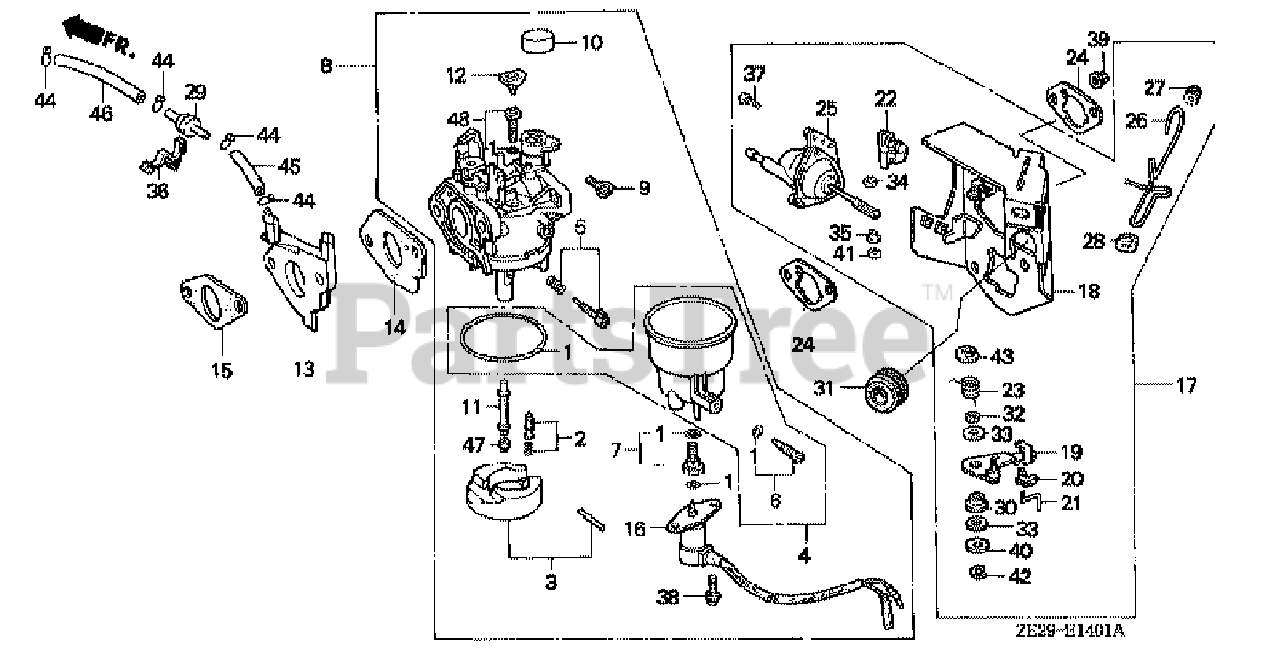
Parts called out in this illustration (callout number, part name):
1	GASKET SET
2	VALVE SET, FLOAT
3	FLOAT SET
4	CHAMBER SET, FLOAT
5	SCREW SET
6	SCREW SET, DRAIN
7	SCREW SET B
8	CARBURETOR ASSY. (BE72C)
9	SCREW, THROTTLE STOP
10	CAP, CHOKE LEVER DUST
11	NOZZLE, MAIN
12	COLLAR, SET
13	INSULATOR, CARBURETOR
14	GASKET, CARBURETOR
15	GASKET, INSULATOR
16	VALVE ASSY., SOLENOID
17	STAY ASSY., MANUAL CHOKE
18	STAY, SOLENOID
19	LEVER, CHOKE
20	JOINT, ROD
21	ROD, CHOKE
22	STOPPER, CHOKE ROD
23	SPRING, MANUAL CHOKE
24	GASKET, AIR CLEANER
25	DIAPHRAGM ASSY.
26	ROD, CHOKE CONTROL
27	GROMMET, CHOKE ROD
28	GUIDE, CHOKE ROD
29	VALVE, DASHPOT CHECK
30	BUSH, ARM PIVOT
31	GROMMET, FENDER
32	WASHER, CHOKE LEVER
33	SEAL, CHOKE LEVER
34	WASHER, THRUST (2.7X8)
35	COLLAR, LEVER
36	CLIP, WIRE HARNESS
37	SCREW, PAN (5X12)
38	SCREW-WASHER (5X12)
39	NUT, FLANGE (6MM)
40	WASHER, PLAIN (5MM)
41	E-RING (2MM)
42	E-RING (4MM)
43	E-RING (7MM)
44	CLIP, TUBE (B7)
45	BULK HOSE, VACUUM (3.5X8000) (3.5X65)
46	BULK HOSE, VACUUM (3.5X8000) (3.5X130)
47	JET, MAIN (#75)
47	JET, MAIN (#78)
47	JET, MAIN (#80)
48	JET SET, PILOT (#45)
